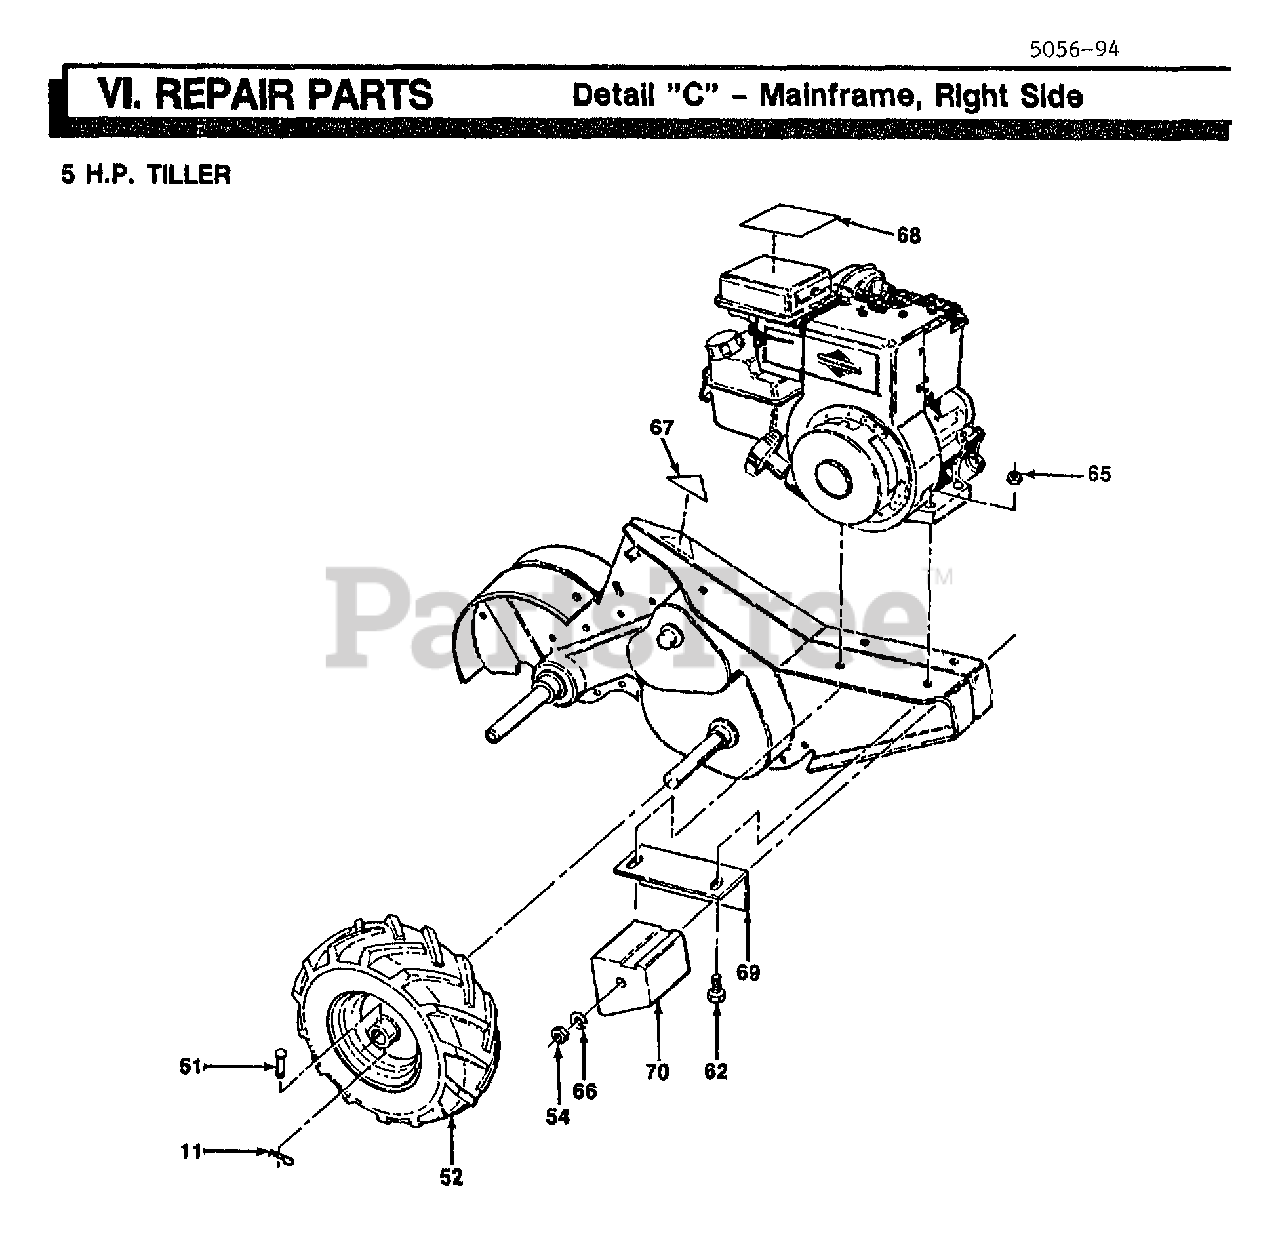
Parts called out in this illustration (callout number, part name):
11	RETAINER M
52A	TIRE.CHV.13X5.0-6
54	NUT.HEX.3/8-16UNC
62	BOLT.HEX.5/16-1.5
66	LOCKWASHER
68	DECAL TI
69	BRACKET RH CRT
70	COUNTERWEIGHT CRT
